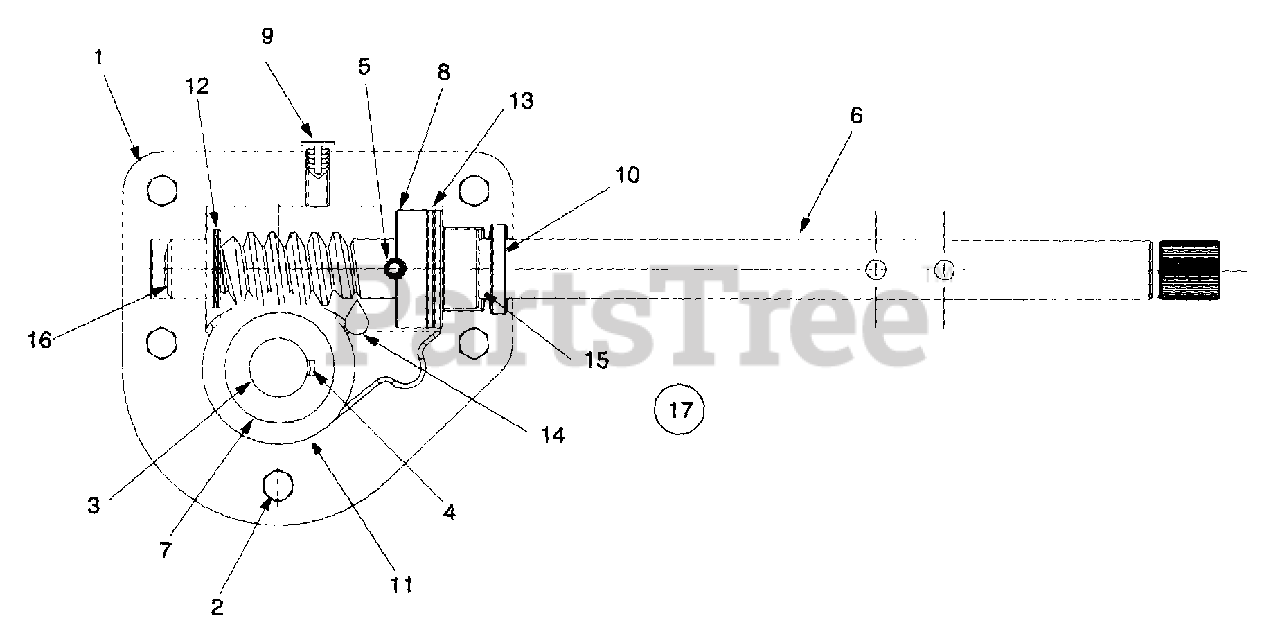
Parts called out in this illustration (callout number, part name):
1	Housing - L.H.
2	Hex Screw 1/4-20 x .75
3	Spiral Axle 26"
4	Key
5	Pin-Spiral
6	Shaft-Worm
7	Gear-Worm
8	Collar-Thrust
10	Seal-Oil
11	Washer-Flat
12	Washer-Flat
13	Washer-Flat
14	Grease
15	Bearing-Flange
16	Bearing-Flange
17	Ass'y. Complete 26"
